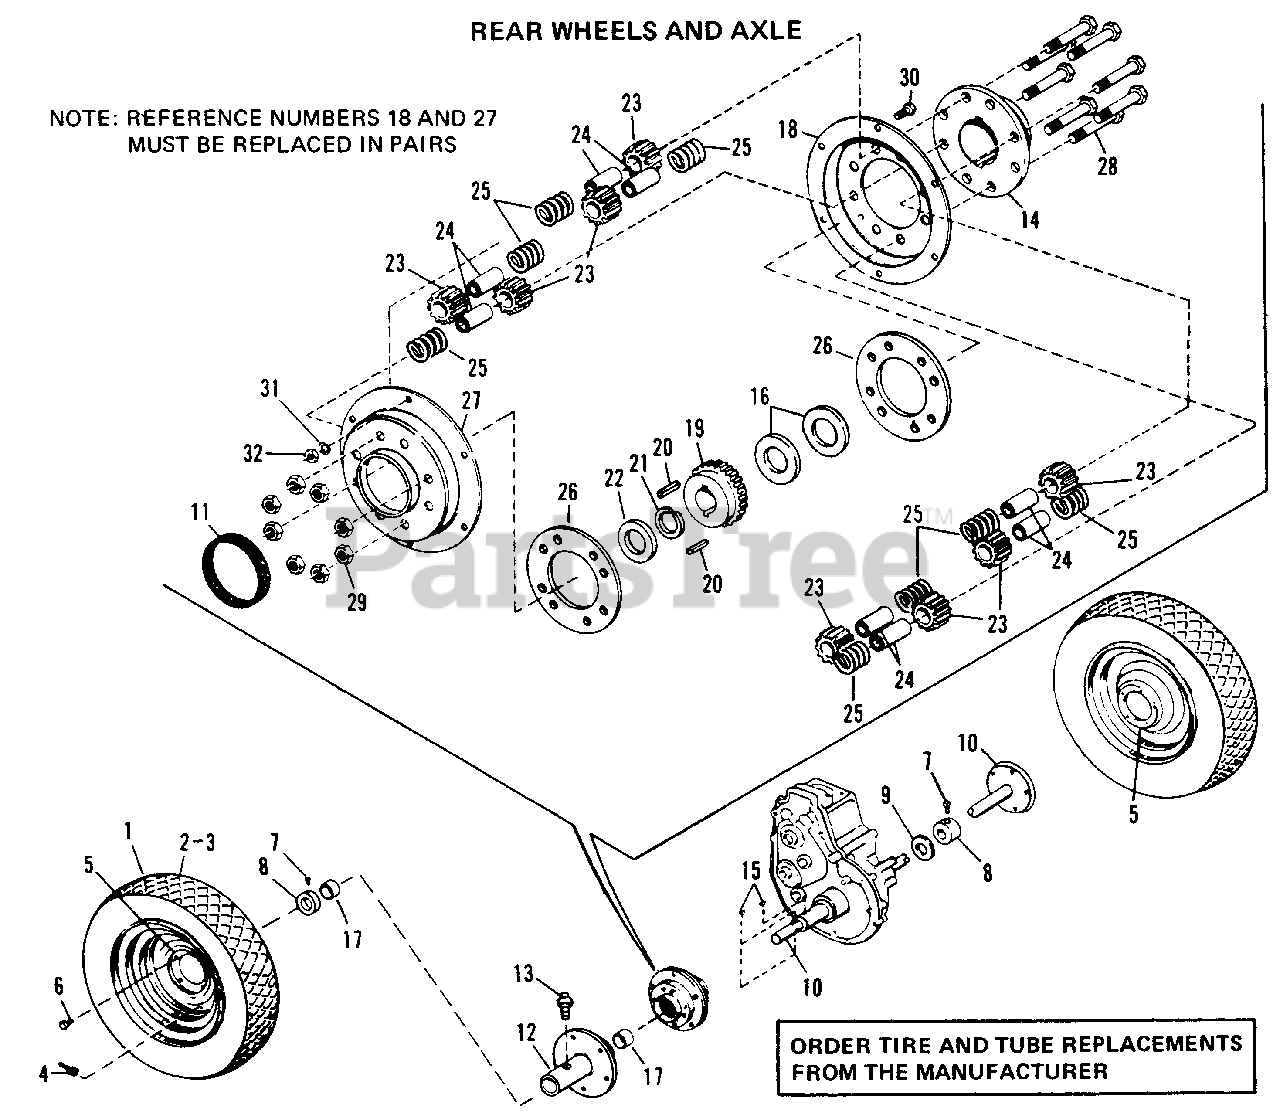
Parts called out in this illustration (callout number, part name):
1	Wheel & Tire Assy.
4	Valve Stem
5	Wheel Drive
7	Set Screw, 5/16"-18 x 3/8"
8	Axle Collar
11	Differential Cover Seal
12	R.H. Wheel Hub Assy.
13	Grease Fitting
14	Differential Carrier
16	Axle Washer
18	Differential Cover
19	Differential Gear
20	Hi-Pro Key
21	Retaining Ring
22	Axle Washer
23	Differential Pinion
24	Differential Pinion Spindle
26	Ring Spacer
27	Differential Cover
28	Hex Capscrew, 3/8"-16 x 2-1/2"
29	Full Hex Lock Nut, 3/8"-16
30	Hex Capscrew, 1/4"-20 x 5/8"
31	Lockwasher, 1/4"
32	Full Hex Nut, 1/4"-20
